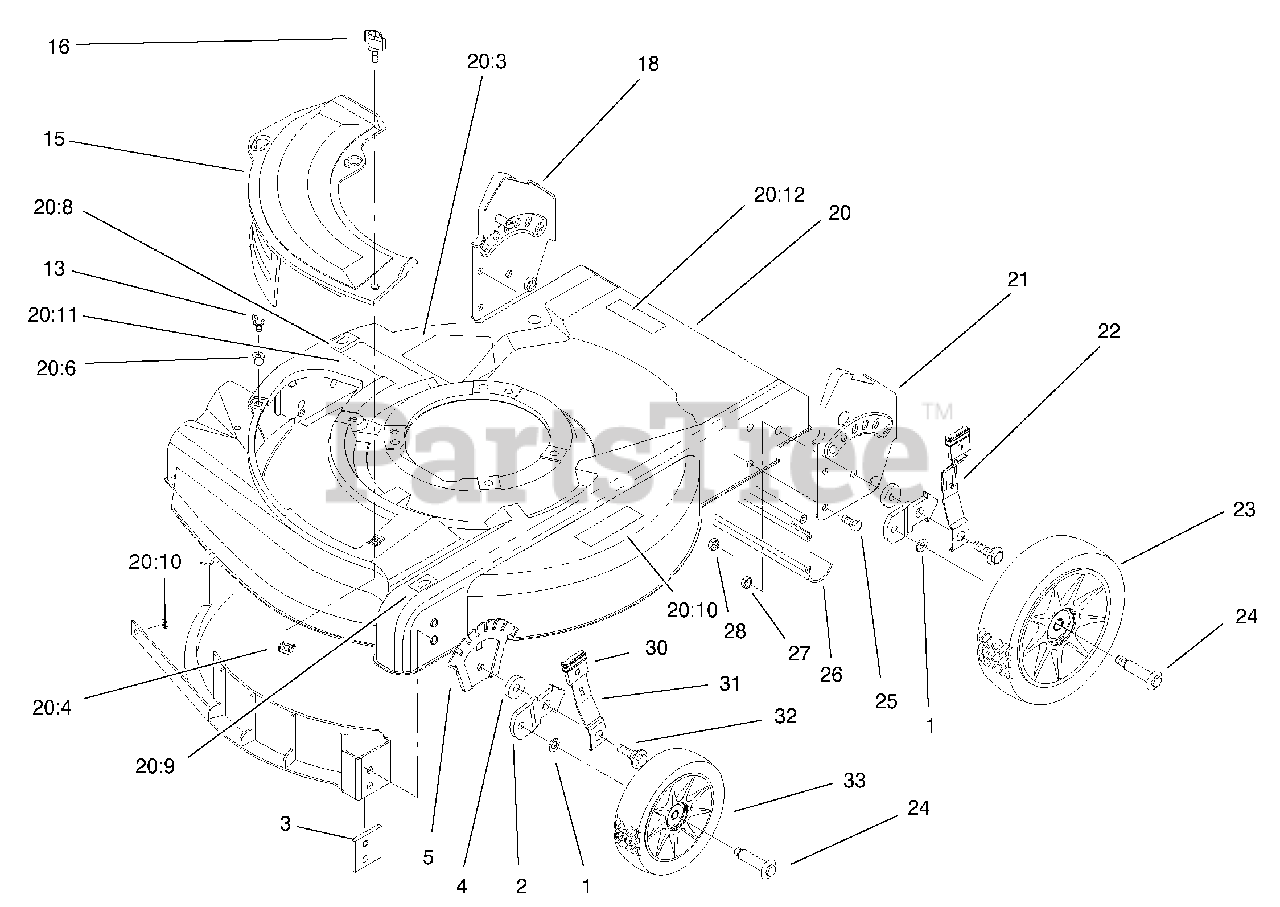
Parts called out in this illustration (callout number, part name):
2	Bracket-Height Adjustment, Wheel
3	Plate-Baffle
4	Washer-Wheel
5	Plate-Height, Adjustment
13	Screw-Sems
15	Plate-Mulch
18	RH Handle Bracket ASM
20:3	Danger Decal
20:4	Nut-Cage
20:6	Grommet-Plastic
20:8	Decal-HOC,RH
20:9	Decal-HOC,LH
20:10	Decal-Warning
20:11	Decal-Warning
20:12	Decal-Manual
21	LH Handle Bracket ASM
22	Rear Spring Arm ASM
23	Wheel & Tire
24	Bolt-Shoulder
25	Screw-HH
26	Shield-Trailing
27	Nut-Lock, NI
28	Nut-Lock, NI
30	Knob-Lever, Height Adjustment
31	Arm-Front Spring
32	Bolt-Shoulder
33	Wheel & Tire
